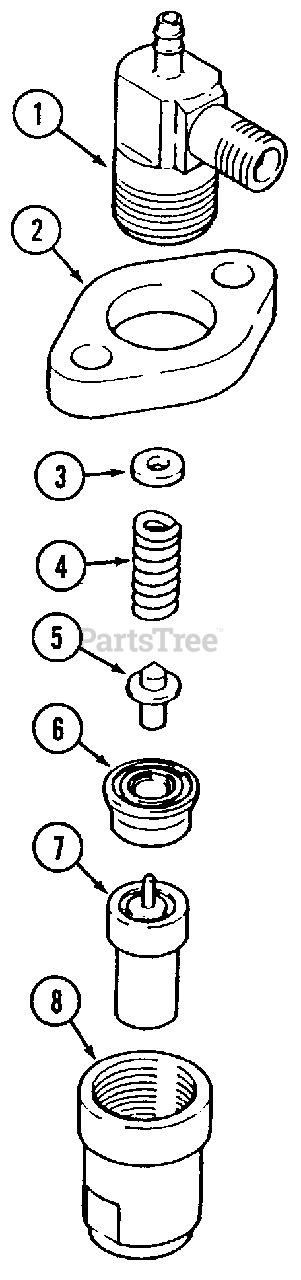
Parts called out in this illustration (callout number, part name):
3	Washer t=1.3
4	Spring, Pressure
5	Pin, Pressure
6	Piece, Distance
7	Nozzle Ass'y.
8	Nut, Retaining
